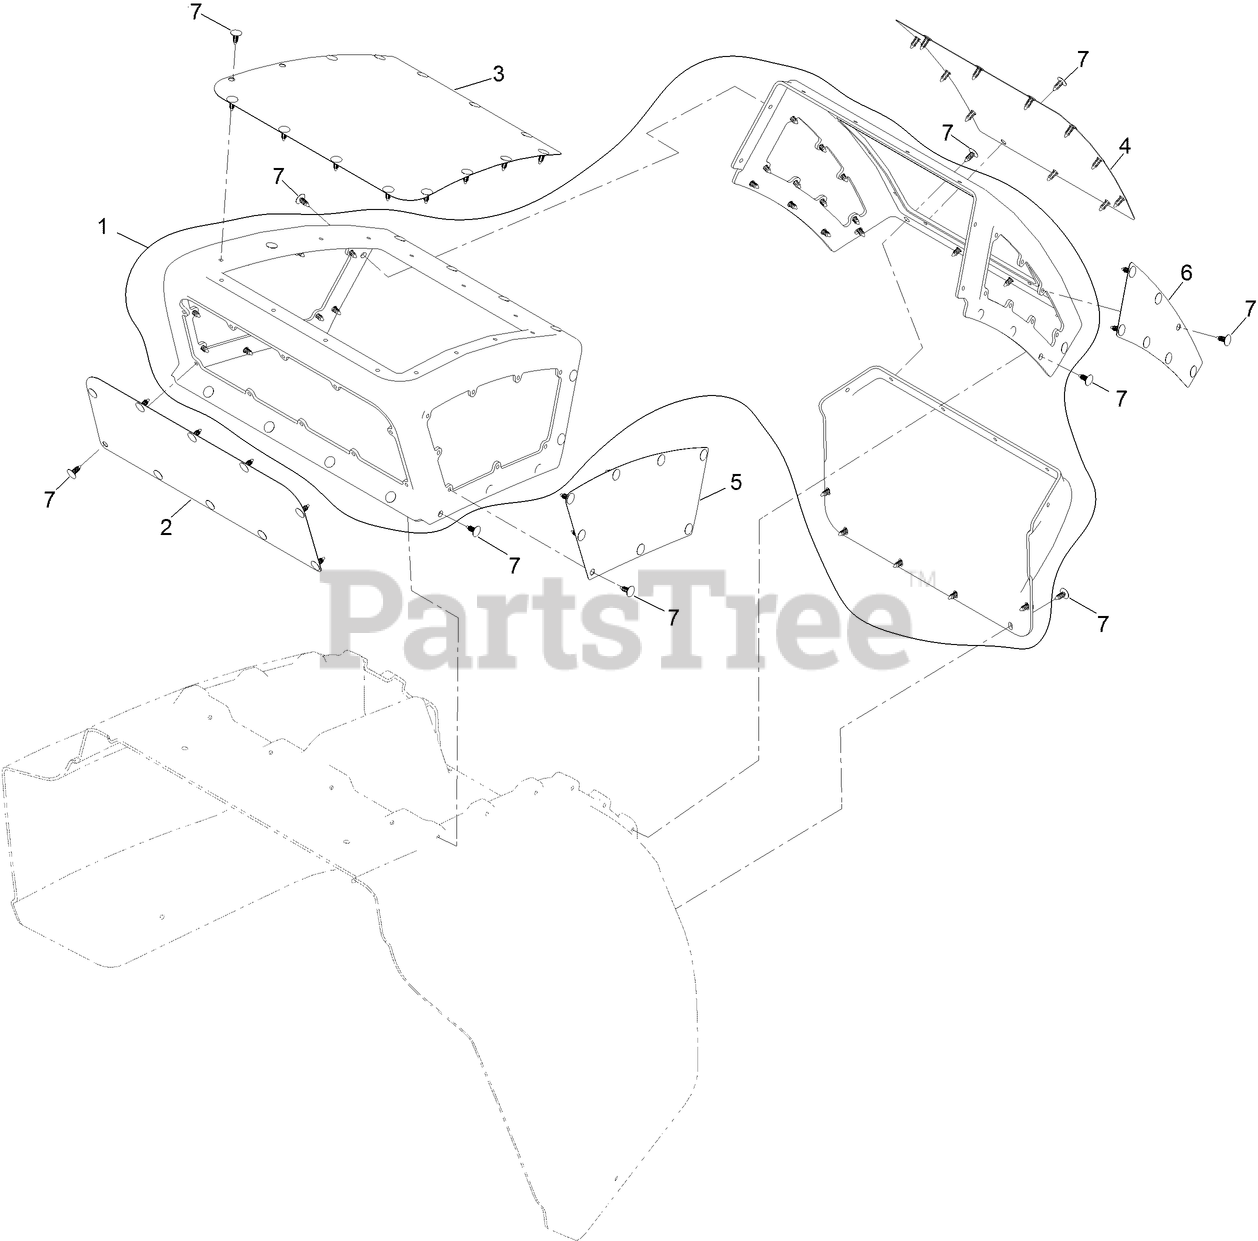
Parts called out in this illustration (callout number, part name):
1	HOOD-INTAKE
2	SCREEN-INTAKE [BLACK]
3	SCREEN-INTAKE [BLACK]
4	SCREEN-INTAKE [BLACK]
5	SCREEN-INTAKE [BLACK]
6	SCREEN-INTAKE [BLACK]
7	PLUG-PLASTIC
